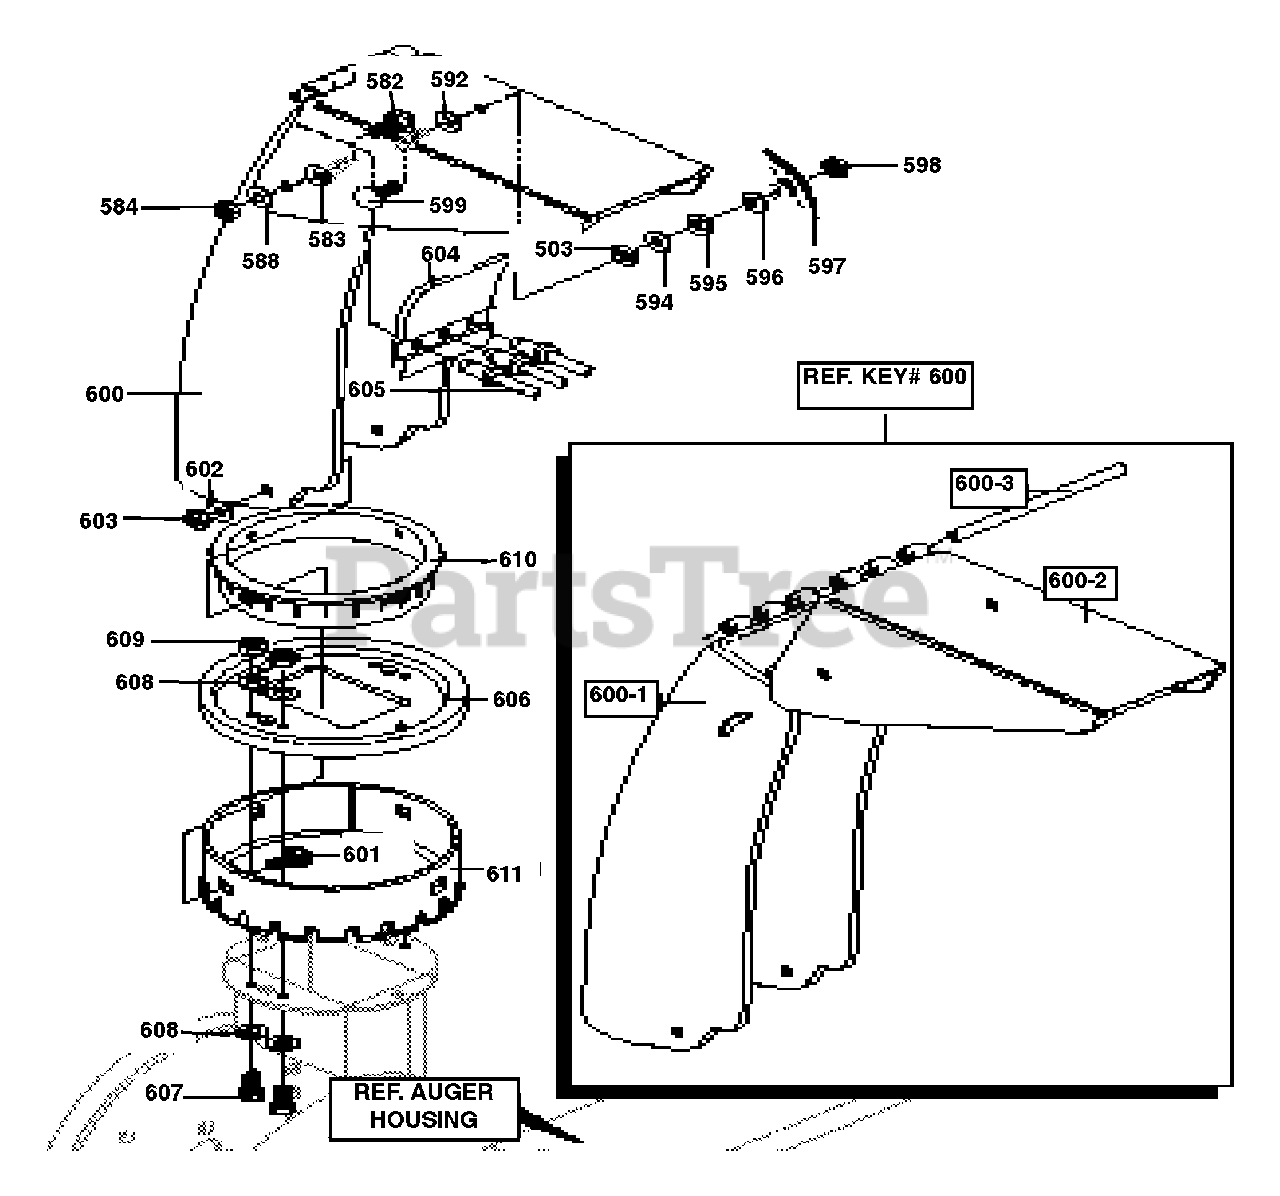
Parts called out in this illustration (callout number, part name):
582	Bolt, 5/16-18 x .75
583	Washer, Pl .438 x .75 x .064
584	Nut, 5/16-18 Reghexctrlk
588	Washer, .315 x .75 x .064
592	Washer, Pl .438 x .75 x .064
593	Washer, .315 x .75 x .064
594	Flatwasher .344 x .69 x .065
595	Washer, .328 x .60 x .09
596	Flatwasher .344 x .69 x .065
597	Knob, T
598	Nut, 5/16-18 Reg hex
599	Bolt, Carr. 5/16-18 x 1.00
600	Chute Assembly
600-1	Lower Chute
600-2	Upper Chute
601	Bolt, 5/16-18 x 1.00
602	Flatwasher, .344 x .69 x .065
603	Nut, 5/16-18 Hex nyl
604	Flap, Chute inset
606	Collar, Chute
607	Screw, 1/4-20 x .75
608	Flatwasher, .281 x .63 x .065
609	Nut, 1/4-20 Reghexctrlk
610	Retainer, Ring Inner
611	Retainer, Ring Outer
